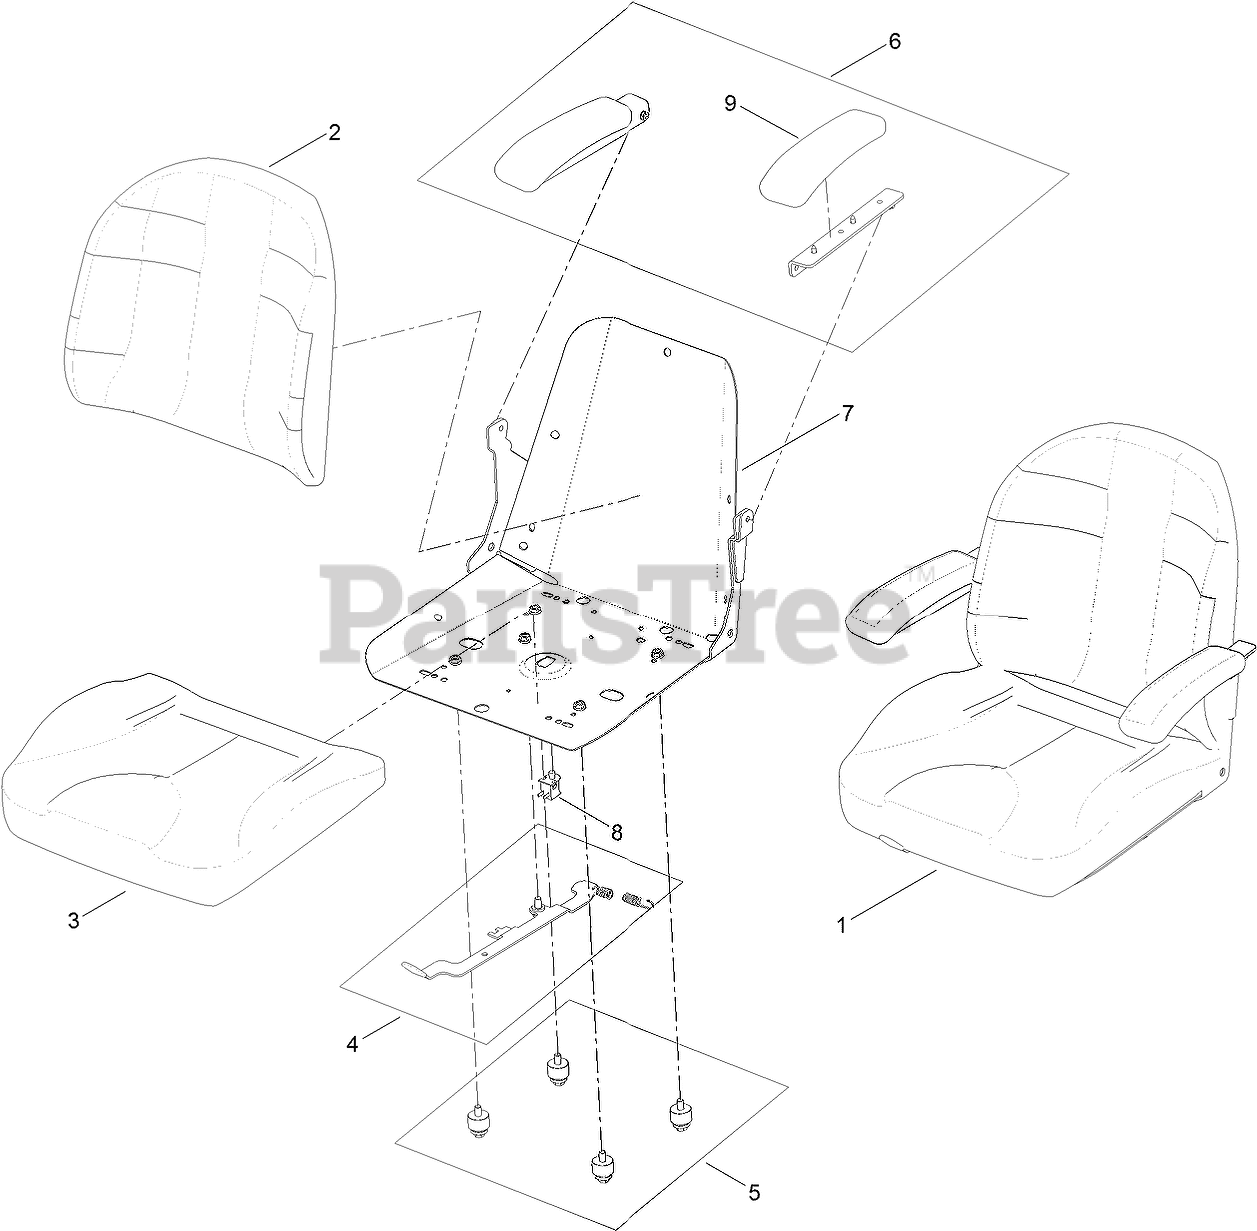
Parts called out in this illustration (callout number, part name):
1	SEAT ASM
2	CUSHION-SEAT, BACK
3	CUSHION-SEAT, BOTTOM
4	TRACK ASM
5	BUSHING ASM
6	ARMREST KIT
8	SWITCH-BAIL
9	CUSHION-REST, ARM
